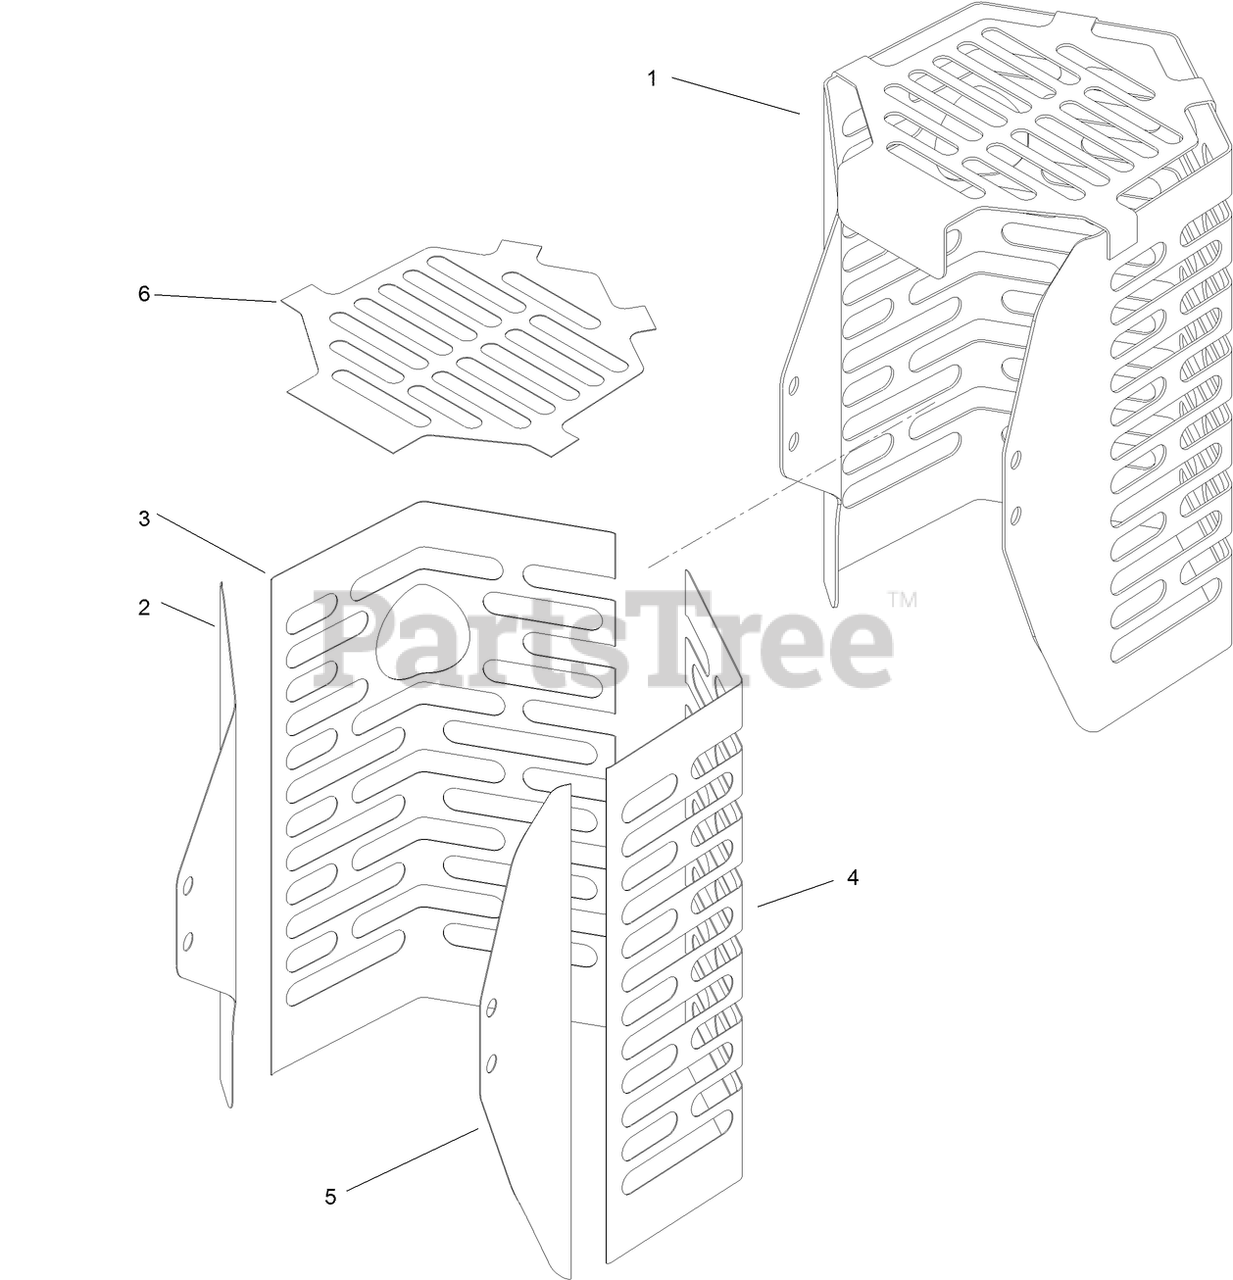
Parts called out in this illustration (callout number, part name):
1	SHIELD-MUFFLER
2	FOIL-SHIELD, LEFT
3	FOIL-SHIELD, SIDE
4	FOIL-SHIELD, FRONT
5	FOIL-SHIELD, RIGHT
6	FOIL-SHIELD, TOP
